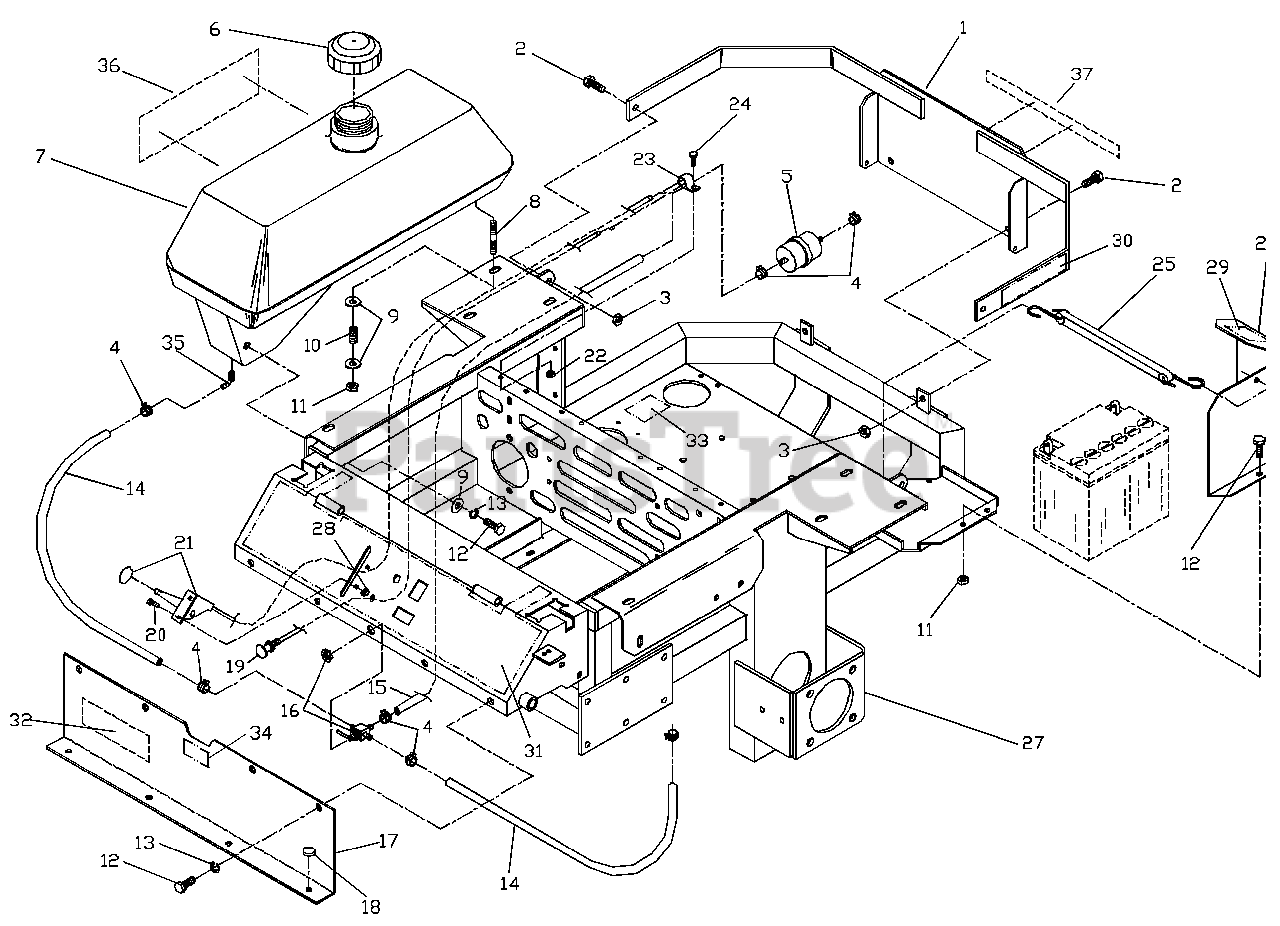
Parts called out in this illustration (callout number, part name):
1	REAR ENGINE GUARD W / DECAL
2	3/8C X 1 HEX CAP SCREW
3	3/8C CENTERLOCK NUT
4	HOSE CLAMP
5	FUEL FILTER
8	5/16C STUD
9	5/16 SAE FLAT WASHER
11	5/16C CENTERLOCK NUT
12	5/16C X 3/4 HEX CAP SCREW GR 5
13	5/16 LOCK WASHER
14	FUEL LINE, TANK
15	FUEL LINE, ENGINE
16	FUEL VALVE
17	KICK PLATE
19	CHOKE CONTROL, COMPLETE
20	#10-24 X 1/2 HEX CAP SCREW
21	THROTTLE CONTROL W / KNOB
22	1/4C CENTERLOCK NUT
24	1/4C X 3/4 HEX CAP SCREW
25	BATTERY STRAP
26	BATTERY GUARD W / DECAL
27	REAR FRAME W / DECAL
28	#10 - 24 NYLOC NUT
29	DECAL, WARNING
30	DECAL, BATTERY
31	DECAL, CONSOLE
32	DECAL, NASCAR
33	DECAL, EXHAUST
34	DECAL, FUEL VALVE
35	90 DEG. HOSE BARB
36	DECAL, ZTH 5223
36	DECAL, ZTH 5225
36	DECAL, ZTH 6125
37	DECAL, HUSQVARNA
